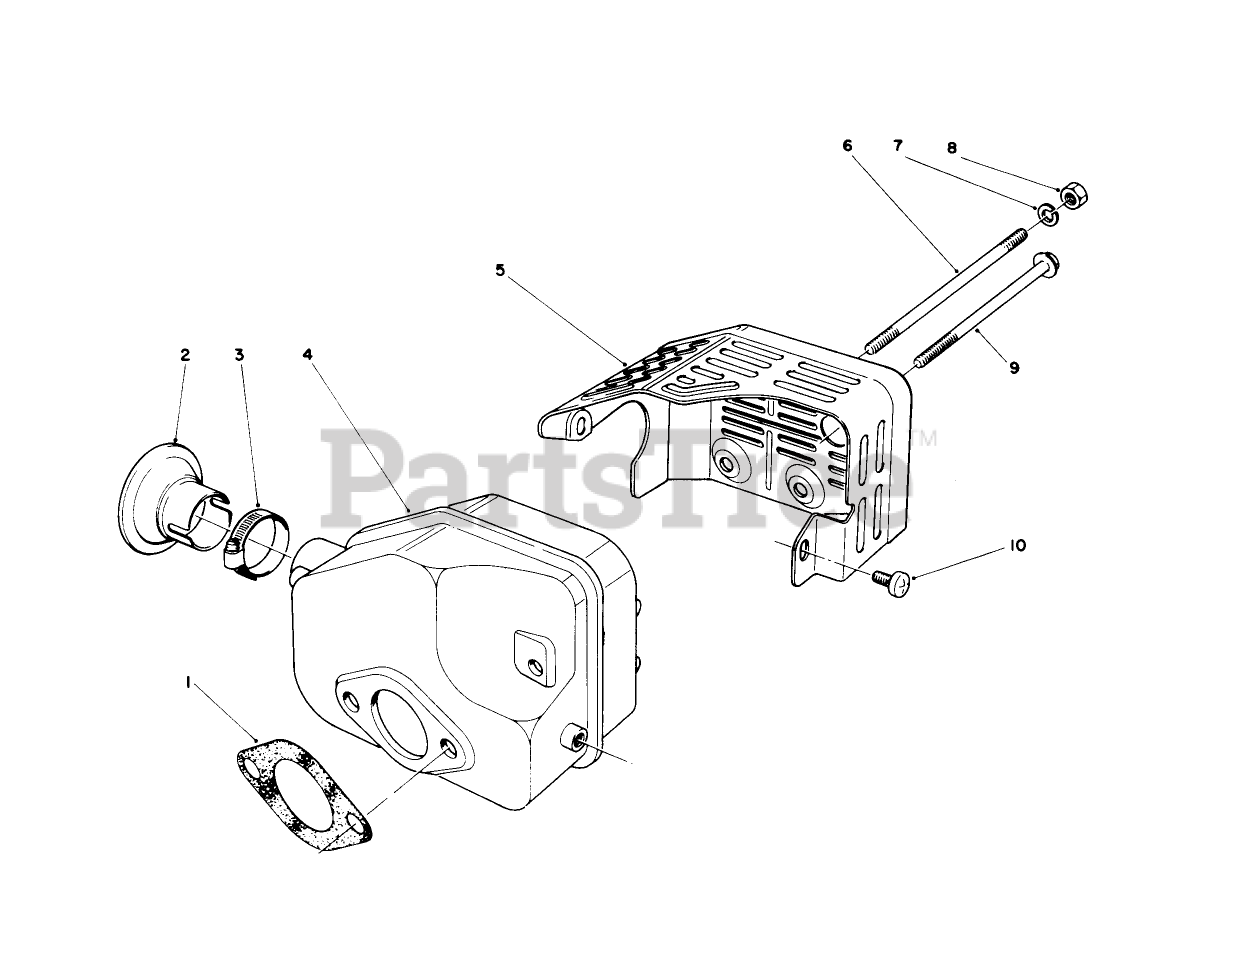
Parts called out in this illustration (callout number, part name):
1	GASKET
3	Clamp
4	MUFFLER
5	COVER-MUFFLER
7	WASHER-LOCK
10	SCREW
